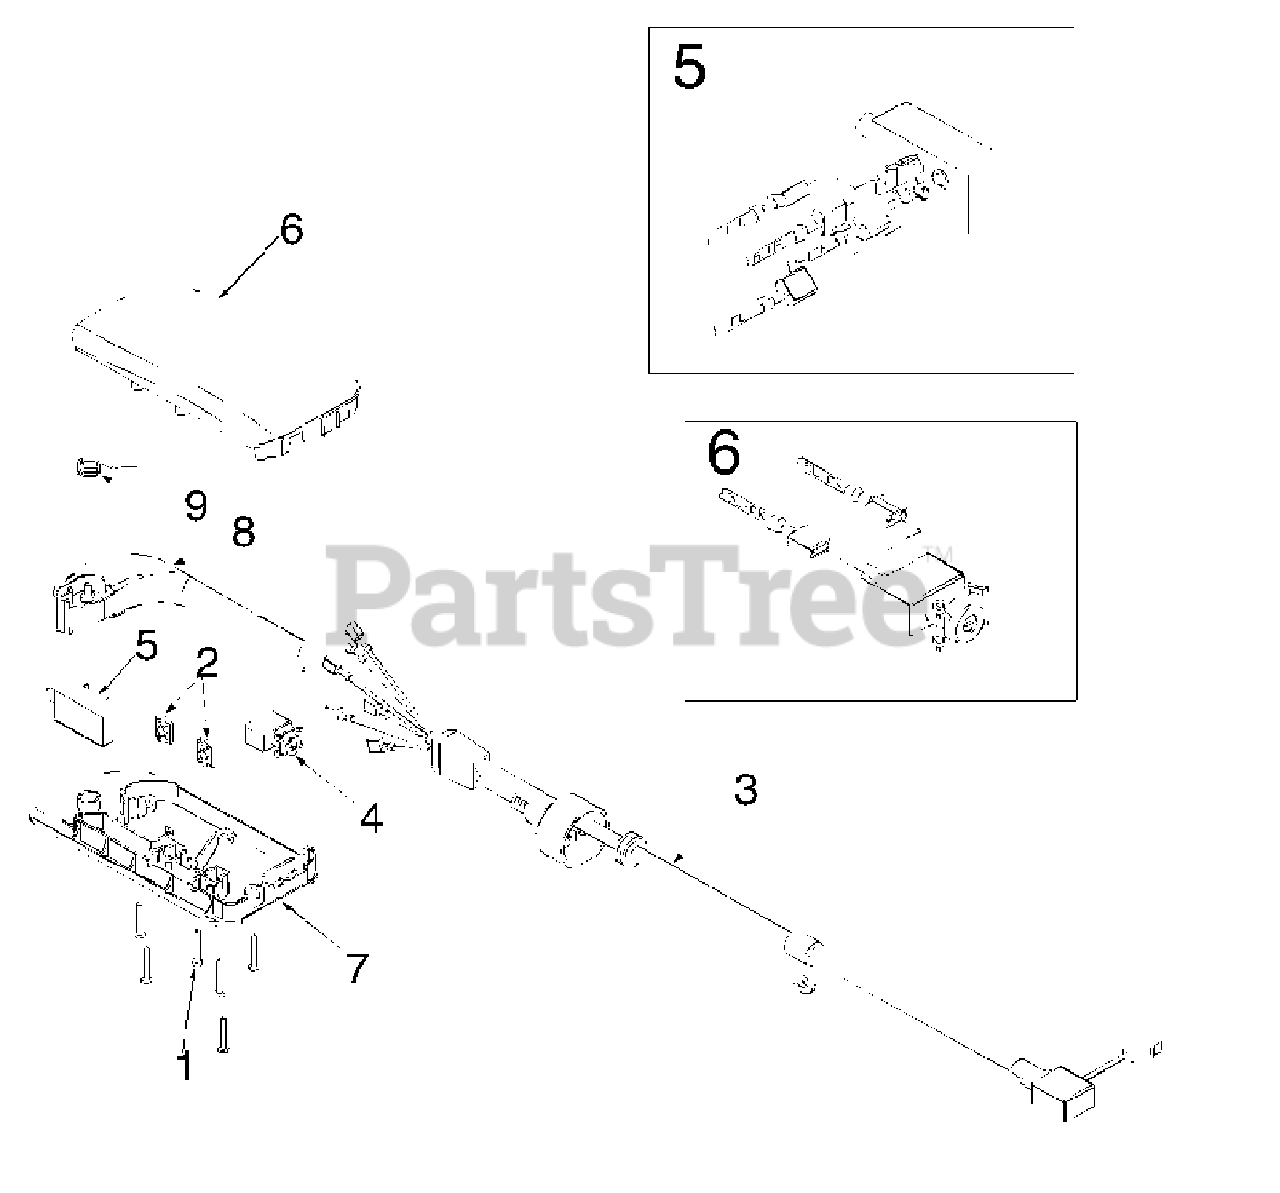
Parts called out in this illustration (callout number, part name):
1	Scr. Hx . Lock #7-19 X 1.00 Lg.
2	Nut Weld Tab 1/4-20 Thd.
4	Circuit Breaker
6	Upper Switch Housing
7	Lower Switch Housing
8	Control Lever
9	Torsion Spring
